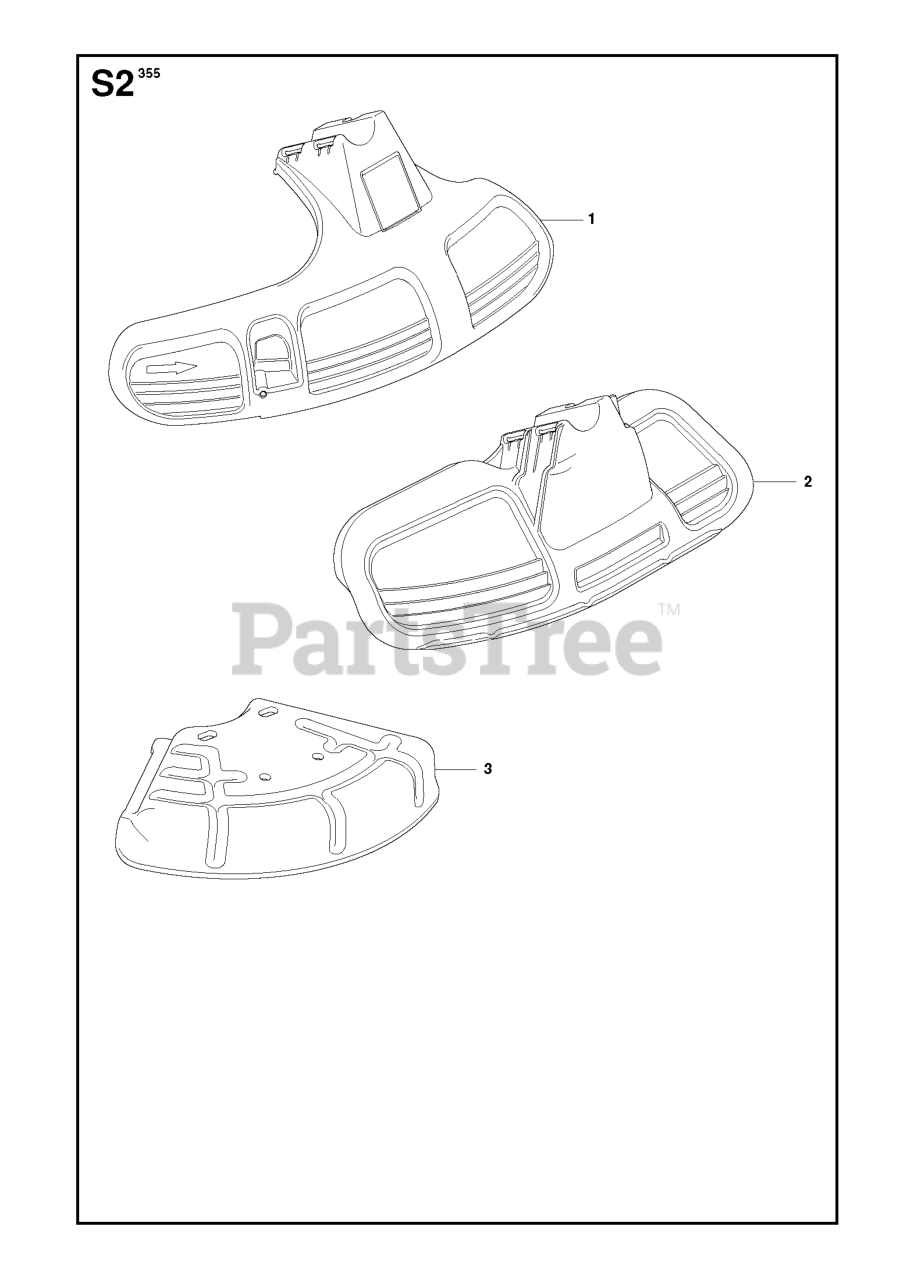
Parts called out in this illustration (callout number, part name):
1	PROTECTION
2	BLADE GUARD GRASS
3	BLADE GUARD SAW
